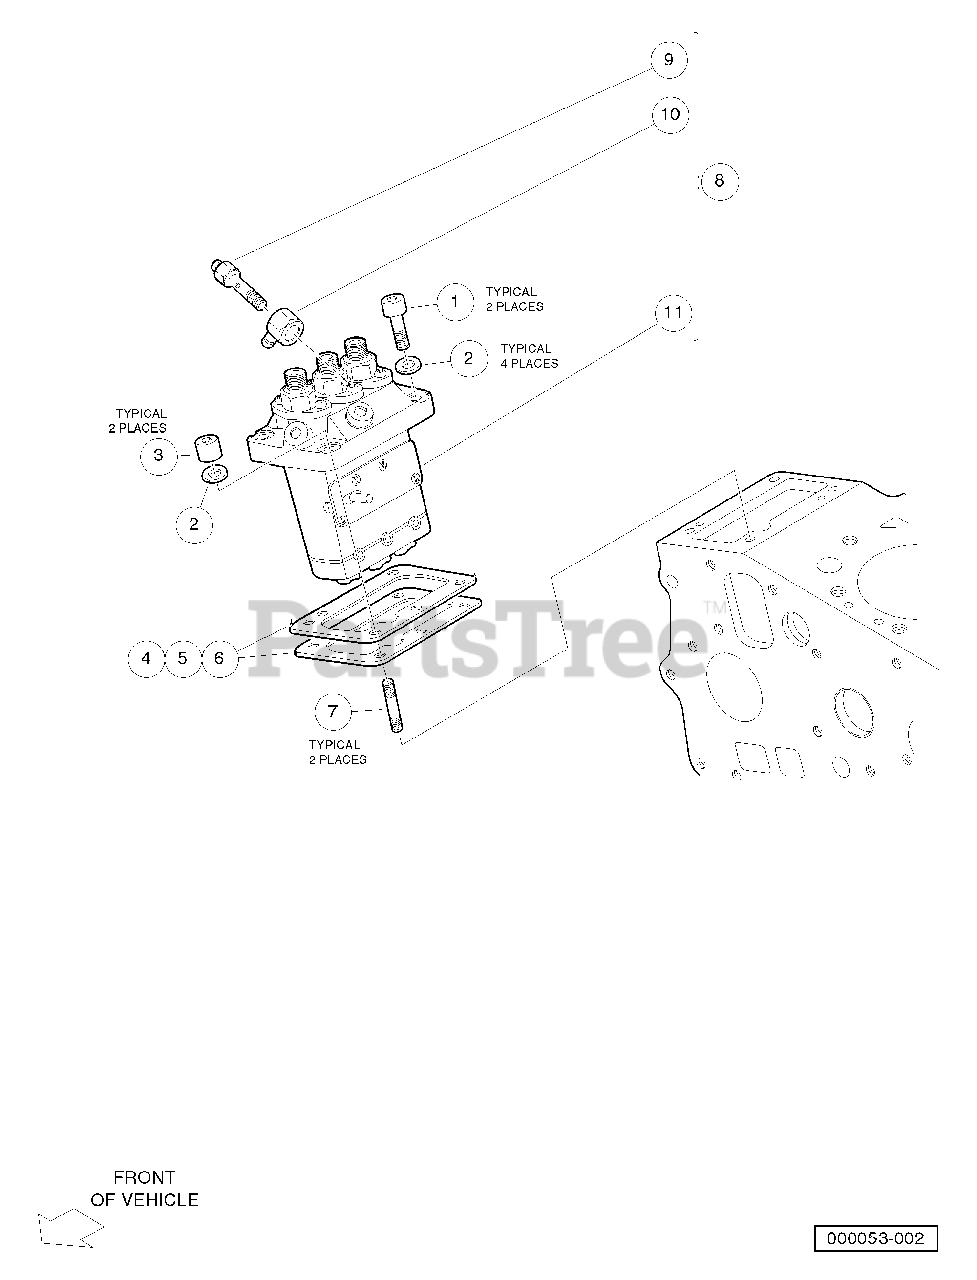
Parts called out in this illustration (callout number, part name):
1	Bolt, Hex-Head, M5 X 0.75 X
2	Washer, Spring, M6, D722
3	Nut, Special
4	Shim, Injection Pump, 0.20 mm
5	Shim, Injection Pump, 0.25 mm
6	Shim, Injection Pump, 0.30 mm
7	Stud, M5 X 25
8	Assembly, Fuel Injection Pump
9	Screw, Hollow, D722, Inj Pump
10	Joint, Eye
11	Pump, Injection
